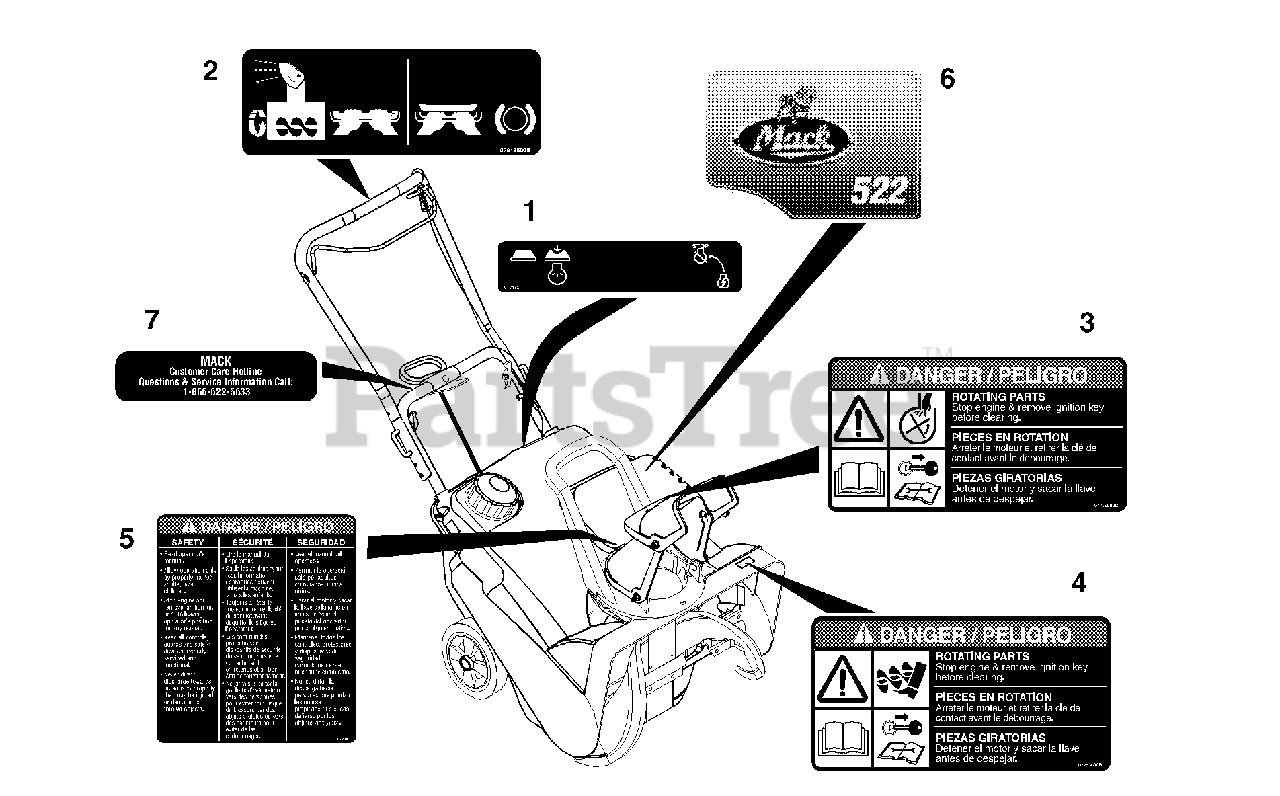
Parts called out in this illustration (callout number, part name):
1	DECAL-PANEL
2	DECAL-AUGER/IMPELLER BAIL
3	DECAL, DANGER - ROT. PARTS
4	DECAL-DANGER AUGER (SS)
5	DECAL-DANGER CHUTE (SS)
6	DECAL, 522 - MACK
7	DECAL, MACK'S HOTLINE
